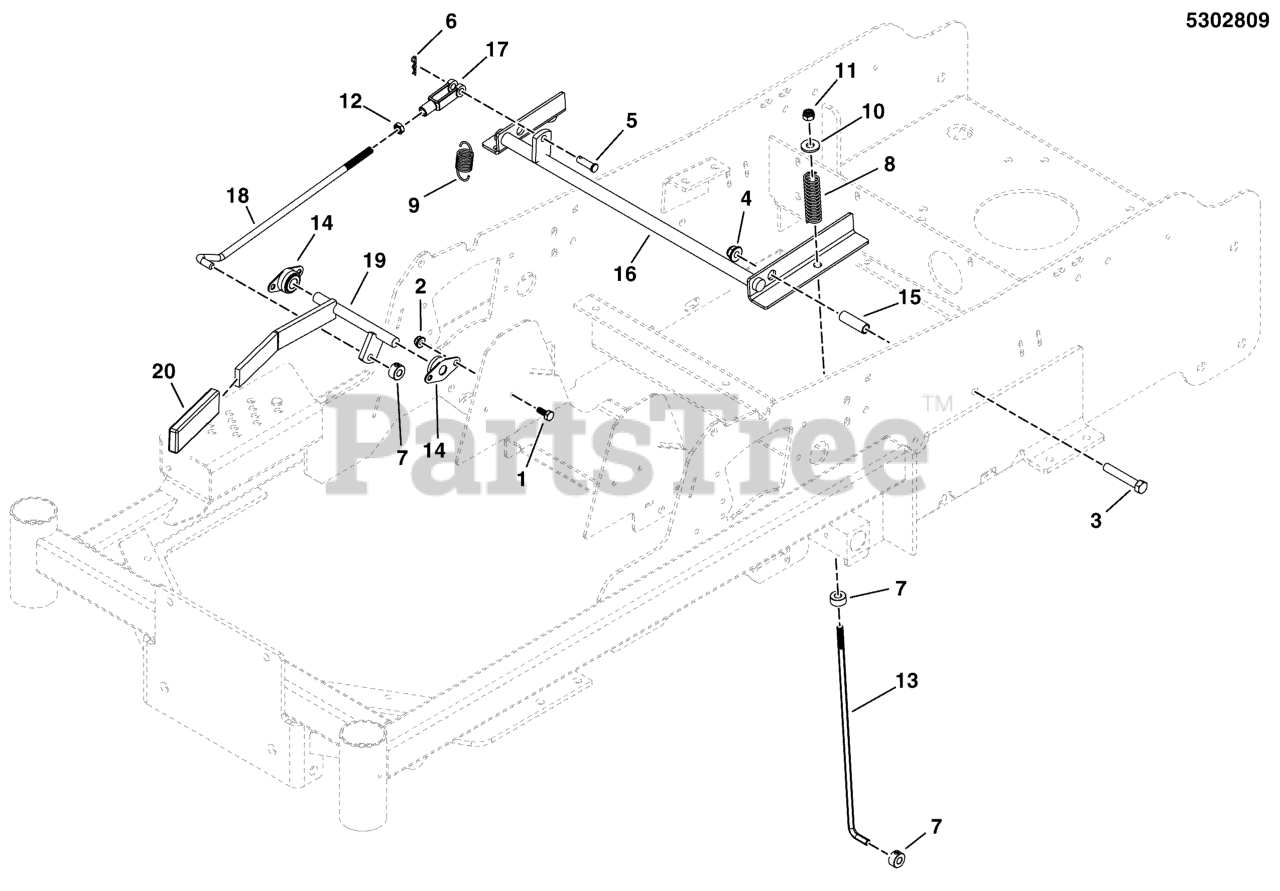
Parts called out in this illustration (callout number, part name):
1	HHCS, 1/4-20 X 0.625, GR5, ZINC/CLEAR
2	NUT, 1/4-20 HEX NYLOCK FLANGE
3	BOLT, 3/8-16 X 2-1/4" GD5 CZ
4	NUT, 3/8-16 HEX NYLOCK FLANGE
5	PIN, CLEVIS, 5/16 X 1 YZ
6	PIN, HAIR, .0585 X 1-1/8, 1/4 EYE, YZ
7	COLLAR, 5/16" SET
8	SPRING, COMPRESSION
9	SPRING; CLUTCH HANDLE
10	WASHER, 5/16 USS
11	NUT, 5/16-24 HEX NYLON LOCK
12	NUT, 5/16-24 JAM
13	ROD, BRAKE CTRL, LOWER - CONZ
14	BEARING, 1/2" FLANGED
15	SPACER, .38 X .50 X 1.56
16	WELD, BRAKE SHAFT - BLK
17	CLEVIS, 5/16-24, STEEL, CLEAR ZINC
18	ROD, PULLER ROD
19	WELD, BRAKE SHAFT, HANDLE - BLK
20	GRIP, FOAM, 1/4 X 1 X 4.1
